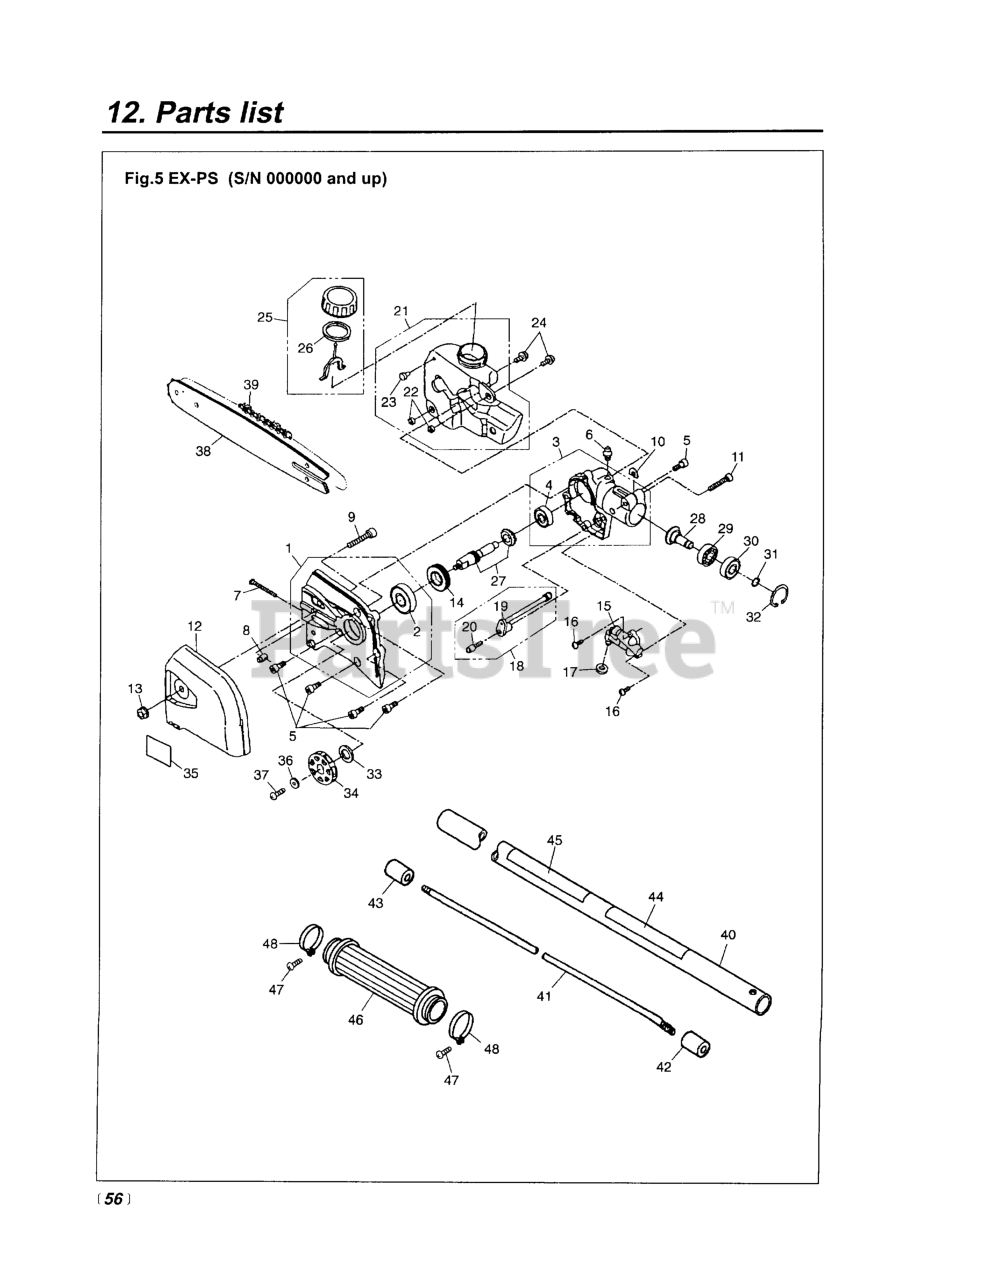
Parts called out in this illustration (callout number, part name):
2	BEARING
3	GEARCASE COMP (RIGHT)
5	BOLT, M5 x 12
6	FITTING, GREASE
7	SCREW
8	NUT
9	BOLT, M6 x 30
10	SHIM
12	COVER, CHAIN
13	NUT
14	GEAR, WORM
15	PUMP ASSY, OIL
16	SCREW, M4 x 10
17	GASKET
18	PIPE ASSY, OIL
19	PIPE, OIL
20	FILTER
21	TANK ASSY, OIL
22	COLLAR
23	VALVE
24	SCREW, M5 X 12
25	CAP ASSY, OIL
26	GASKET, OIL CAP
27	SHAFT, GEAR
28	GEAR, BEVEL
29	BEARING (RPLS T3403-13530)
31	RING, SNAP (RPLS T3300-13330)
32	RING, SNAP, M24 x 1.2
33	COLLAR
34	SPROCKET
35	LABEL (PSZ2500)
36	WASHER
37	SCREW
39	12
40	PIPE COMPLETE
41	SHAFT
42	JOINT, SHAFT (RPLS -12240)
43	SPACER
44	PLATE, NAME (PS-EX)
45	PLATE, CAUTION
46	GRIP
48	SCREW (RPLS 00260- )
